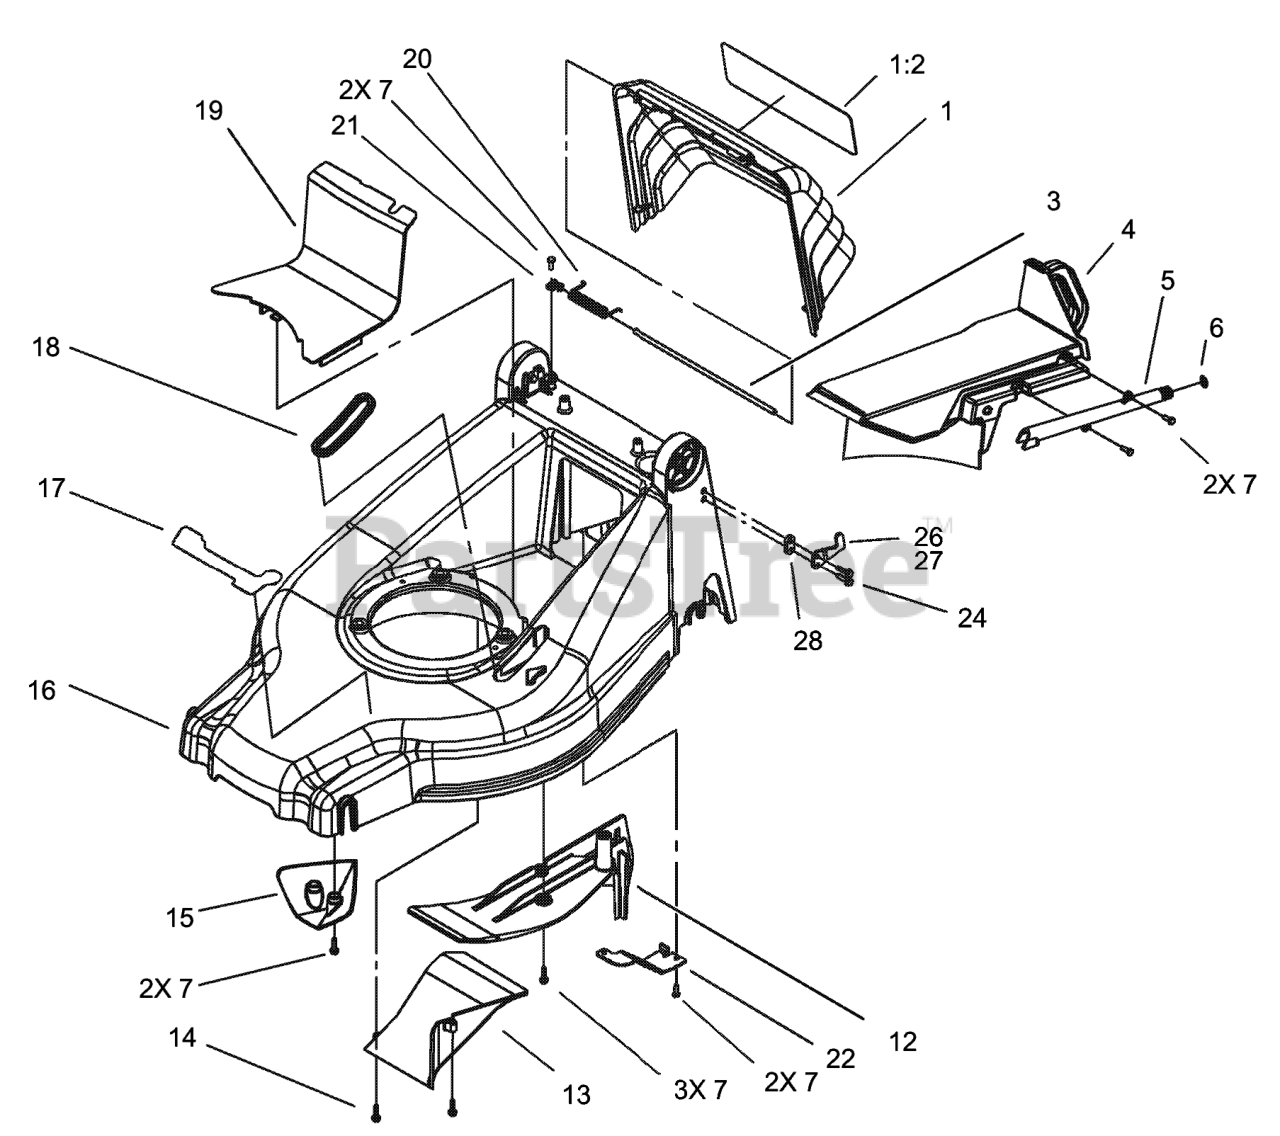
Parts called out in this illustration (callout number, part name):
1	DOOR ASM
1:2	DECAL-DANGER
3	ROD-PIVOT
4	PLUG-KICKER, RECYCLER
5	FITTING-WASHOUT
6	O-RING
7	SCREW-TAPTITE
12	COVER-KICKER, REAR
13	RAMP-DISCHARGE
14	SCREW-HWH
15	KICKER-FRONT
16	Deck
17	DECAL-RECYCLER
18	BOOT-HOC
19	COVER-BELT
20	SPRING-TORSION
21	CLAMP
22	BRACKET-DECK
24	SCREW-HWH
26	HOOK-LEFT
28	SPACER
